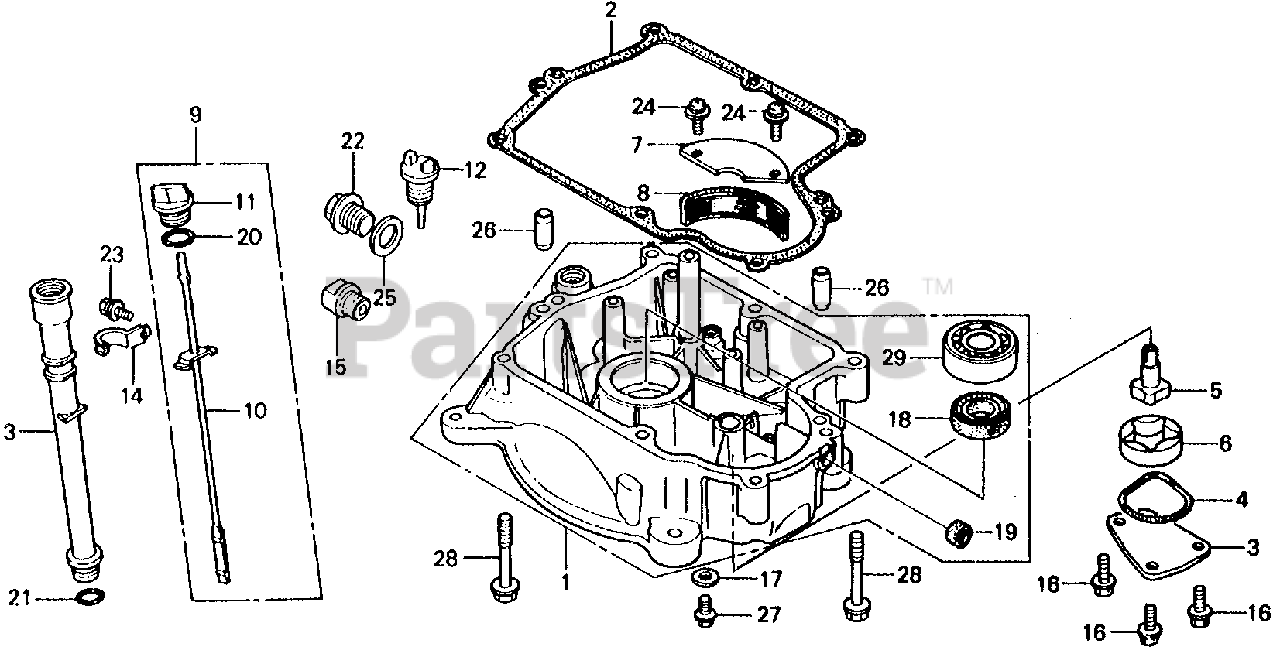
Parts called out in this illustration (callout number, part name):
1	PAN ASSY., OIL
2	GASKET, OIL PAN
3	COVER, OIL PUMP (NOT AVAILABLE)
4	O-RING (39X2.9)
5	ROTOR (INNER)
6	ROTOR, OIL PUMP (OUTER)
7	PLATE, OIL FILTER
8	SCREEN, OIL FILTER
9	GAUGE ASSY., OIL LEVEL
10	DIPSTICK, OIL
11	CAP, OIL
13	EXTENSION, OIL FILLER
14	CLAMP, EXTENSION
15	ADAPTER, OIL DRAIN EXTENSION
16	BOLT, FLANGE (6X12) (CT200)
17	WASHER A (8MM)
18	OIL SEAL (30X46X8)
19	OIL SEAL (6X11X4)
20	O-RING (26X2.7)
21	O-RING (16.8X2.4)
22	BOLT, DRAIN PLUG (20MM)
23	BOLT-WASHER (6X10)
24	SCREW-WASHER (5X12)
25	WASHER, DRAIN PLUG (20MM)
26	PIN A, DOWEL (8X14)
27	BOLT, FLANGE (8X16)
28	BOLT, FLANGE (8X45)
29	BEARING, RADIAL BALL (6206)
